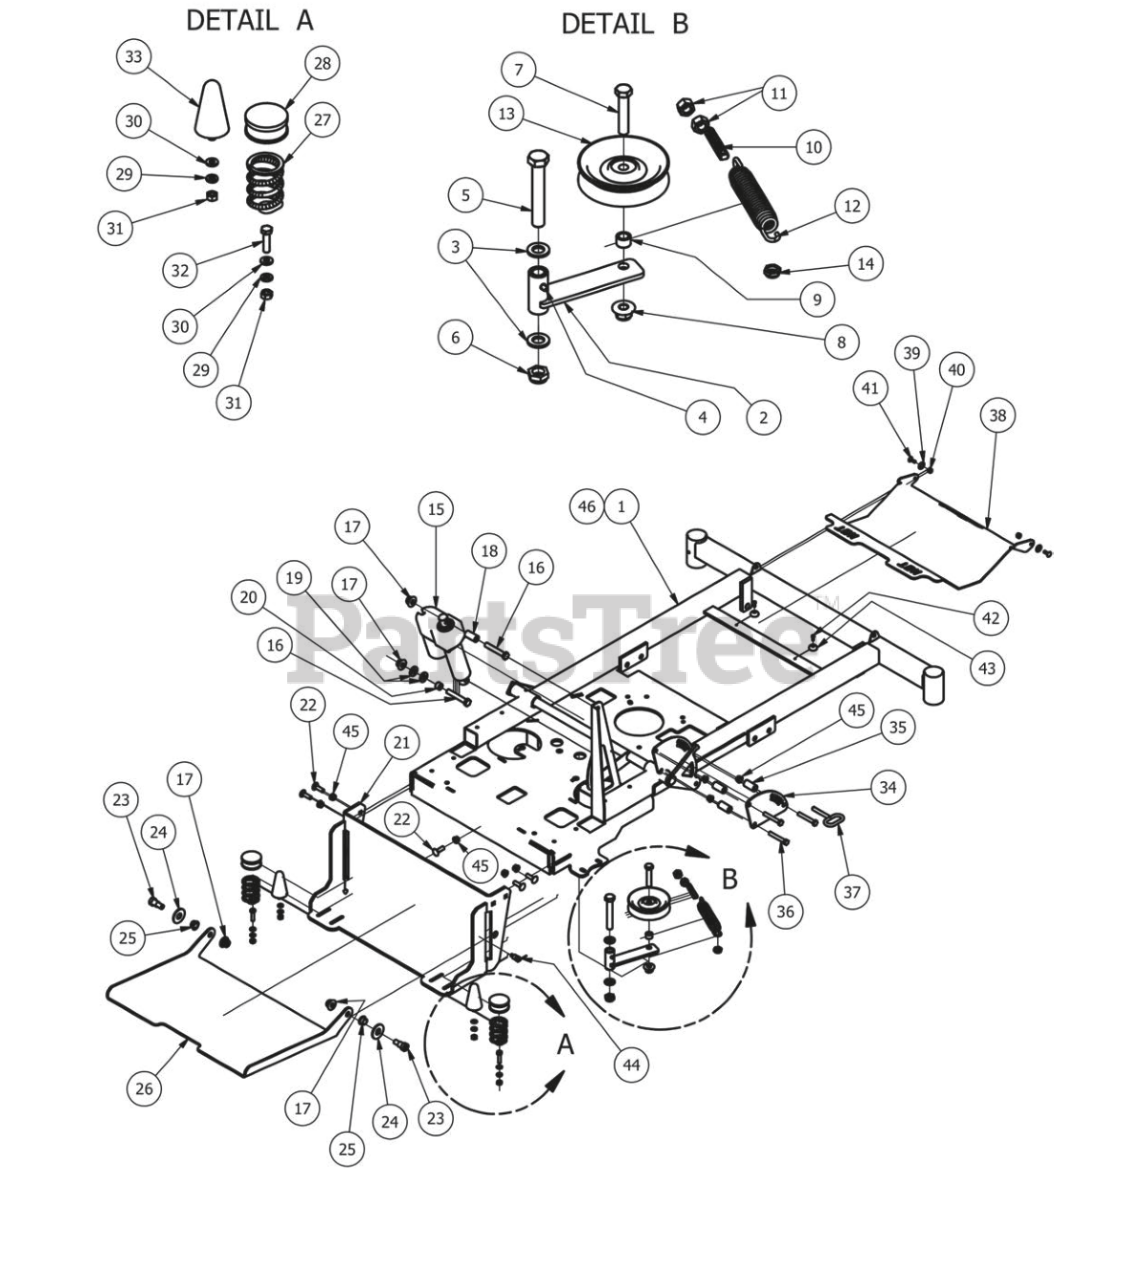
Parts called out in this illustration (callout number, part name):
1	Stand On Frame 2012 (54" Decks)
2	Stand-On Pump Idler Bracket
3	.635 ID Plastic Washer
4	1/4" Drive in Grease Fitting
5	5/8" x 4" Hex Bolt
6	5/8" Nylock (1/2 Jam)
7	1/2" x 2 1/2" Hex Bolt
8	1/2-13 Nylon Flange Nut-Orange
9	1/2 x 1/2 Spacer
10	All Thread-pump Idler Tensioner
11	1/2" Hex Nut
12	2009 Deck/Pump Idler Spring
13	4 3/4" Idler Pulley
14	1/2" Nylcock Nut (1/2 Jam)
16	1/2-13 x GR 5 Hex Bolt Zinc
17	1/2-13 Nylon Flange Nut-Orange
18	1.25" Pulley Spacer
19	.505 Nylon Spacer
20	1/2 x 1/2 Spacer
21	Stand Frame Support
22	3/8" x 1 1/4" Carriage Bolt
23	5/8" x 5/8" Shoulder Bolt
24	5/8" Flat Washer
25	Bronze Bushing - SF-2024-8
26	Stand Plate for Stand On
27	Seat Spring
28	Spring Cap Cover
29	5/16" Lock Washer
30	1/4" Flat Washer
32	5/16 x 1 1/4 Hex Bolt
33	Spring Cushion
34	Height Indicator Plate Stand On (Bolt on)
35	Pup Pulley Spacer
36	3/8 x 2 1/2 Hex Tap Bolt
37	Pin And Lanyard
38	Floor Panel Stand On
39	.360 ID Plastic Washer
40	1/4" Nylock Nut
41	1/4" x 3/4" Carriage Bolt
42	#10 x 1/2" Self Taping Screw
43	Button Bumper
44	Deck Height Pin-Stand On-New
45	3/8" Nylock Flange Nut
46	Stand On Frame (48" Decks)
